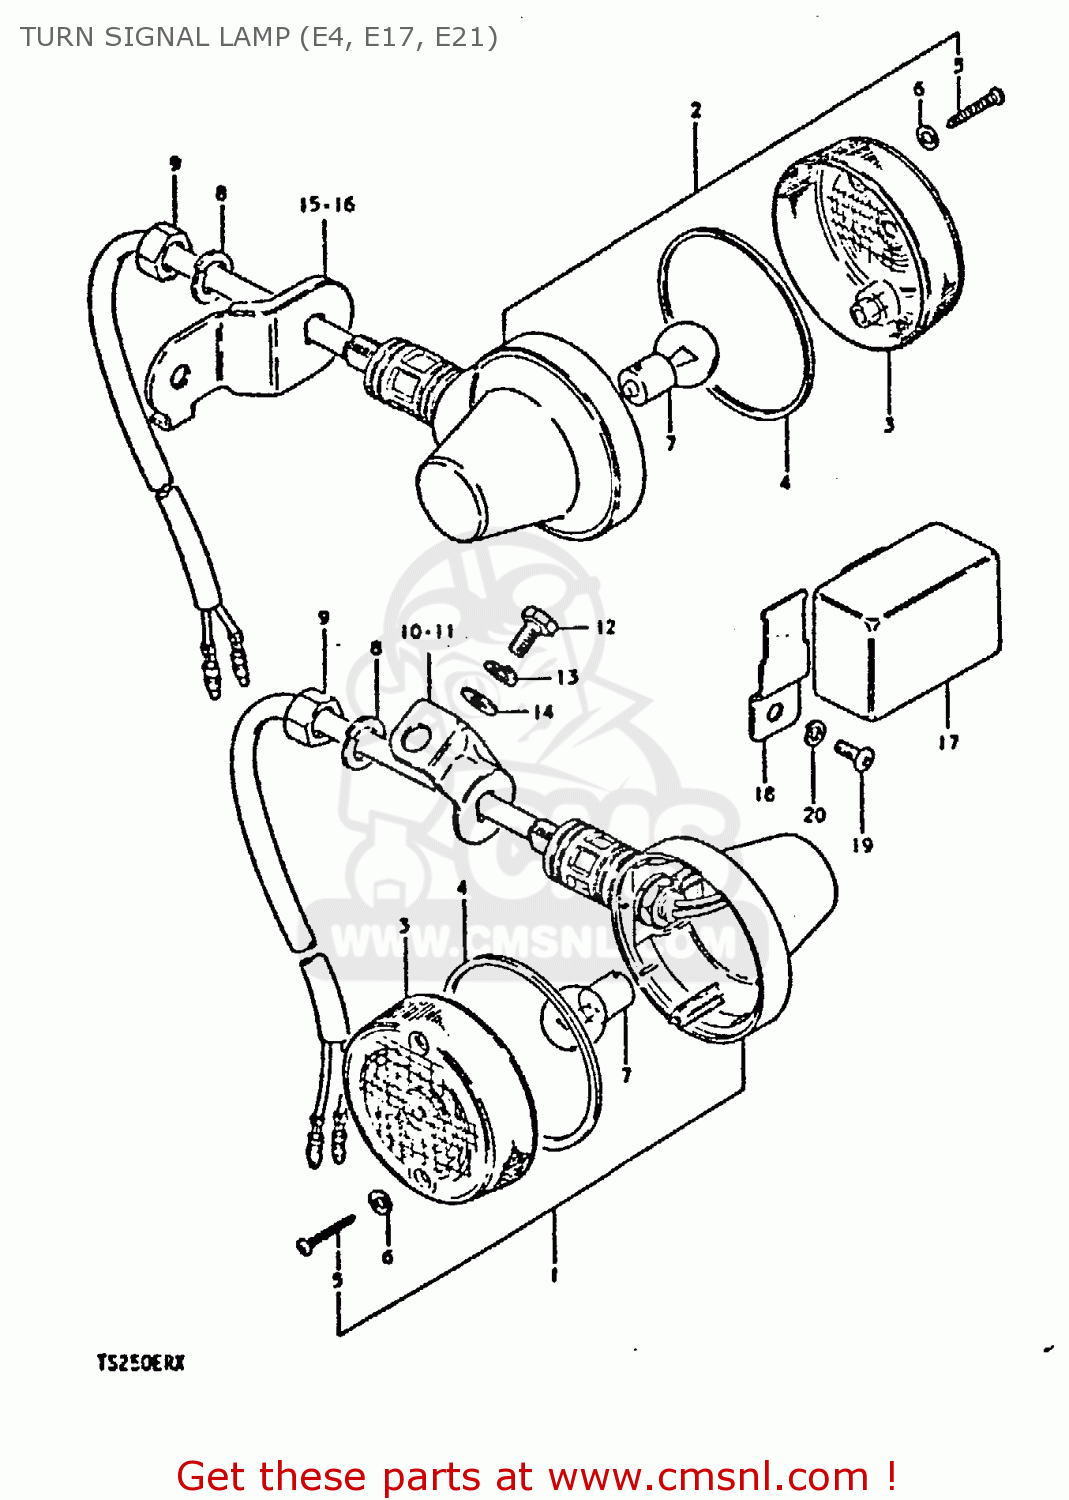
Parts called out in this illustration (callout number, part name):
1	LAMP ASSY,RR TURNSIGNAL
2	LAMP, REAR TURN SIGNAL
3	LENS
4	GASKET (NAS)
5	SCREW TAPP.
6	GASKET (NAS)
7	BULB(6V/10W,STANLEY,A4117)
8	WASHER,LOCK 12
9	NUT
10	BRACKET,TURN SIGNAL LAMP
11	BRACKET,TURN SIGNAL LAMP
12	BOLT
13	LOCK WASHER
14	WASHER
15	BRACKET,REAR TURN SIGNAL
16	BRACKET,REAR TURN SIGNAL
17	RELAY, TURN SIGNAL
18	BRACKET,TURN SIGNAL RELAY
19	SCREW 6X12
20	LOCK WASHER
